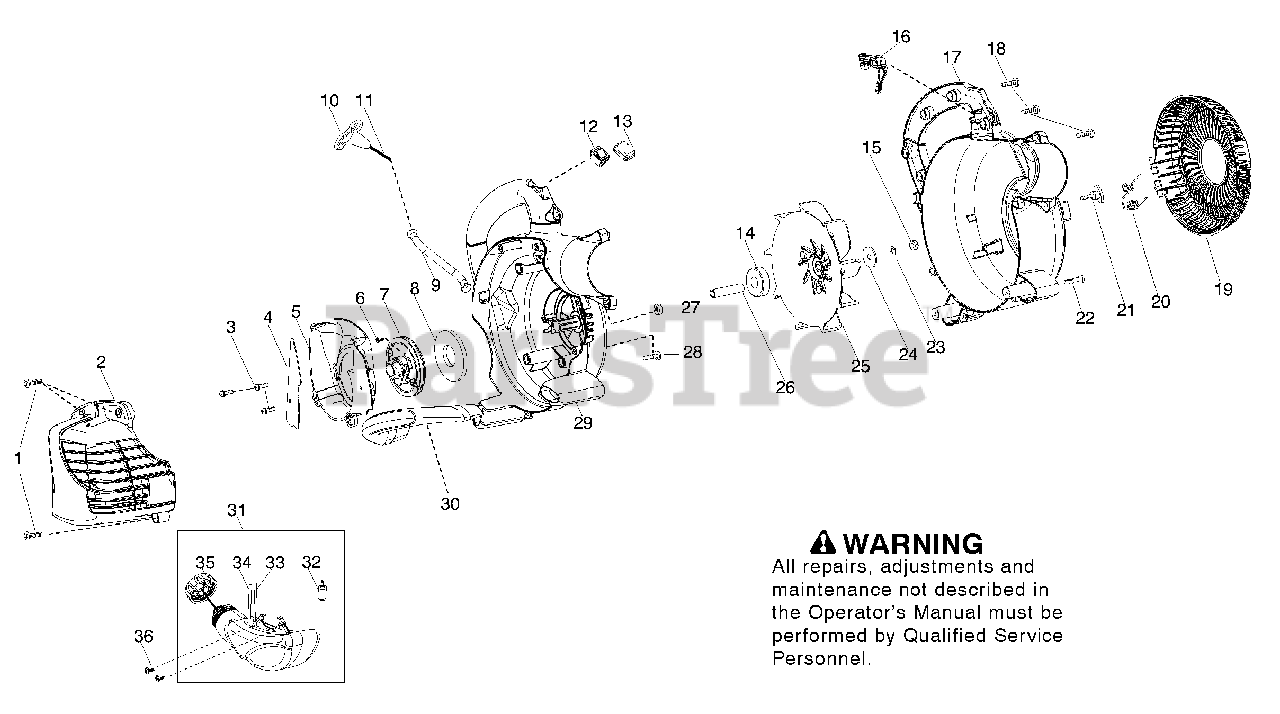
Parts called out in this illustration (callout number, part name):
2	Assy - Engine Cover
4	Shield - Baffle
7	Kit - Starter Pulley
8	Spring - Starter
9	Tube - Starter Rope
10	Handle - starter
12	Kit - Switch (momentary)
13	Protector - Switch
16	Trigger - Throttle
17	Assy - Scroll LH
20	Spring - Vac Door
21	Knob - Blower
22	Screw - Handle Vac
23	Washer - Lock
24	Washer - Impeller
25	Assy-Impeller
26	Spacer - Flywheel
28	Screw
29	Assy-Scroll Assy. RH
31	Assy - Fuel Tank
32	Assy - Fuel Pickup
33	Kit - Fuel Line (carb/purge)
34	Kit - Fuel Line (tank/purge)
35	Assy - Fuel Cap w/retainer
36	Screw - Fuel Tank Retainer
